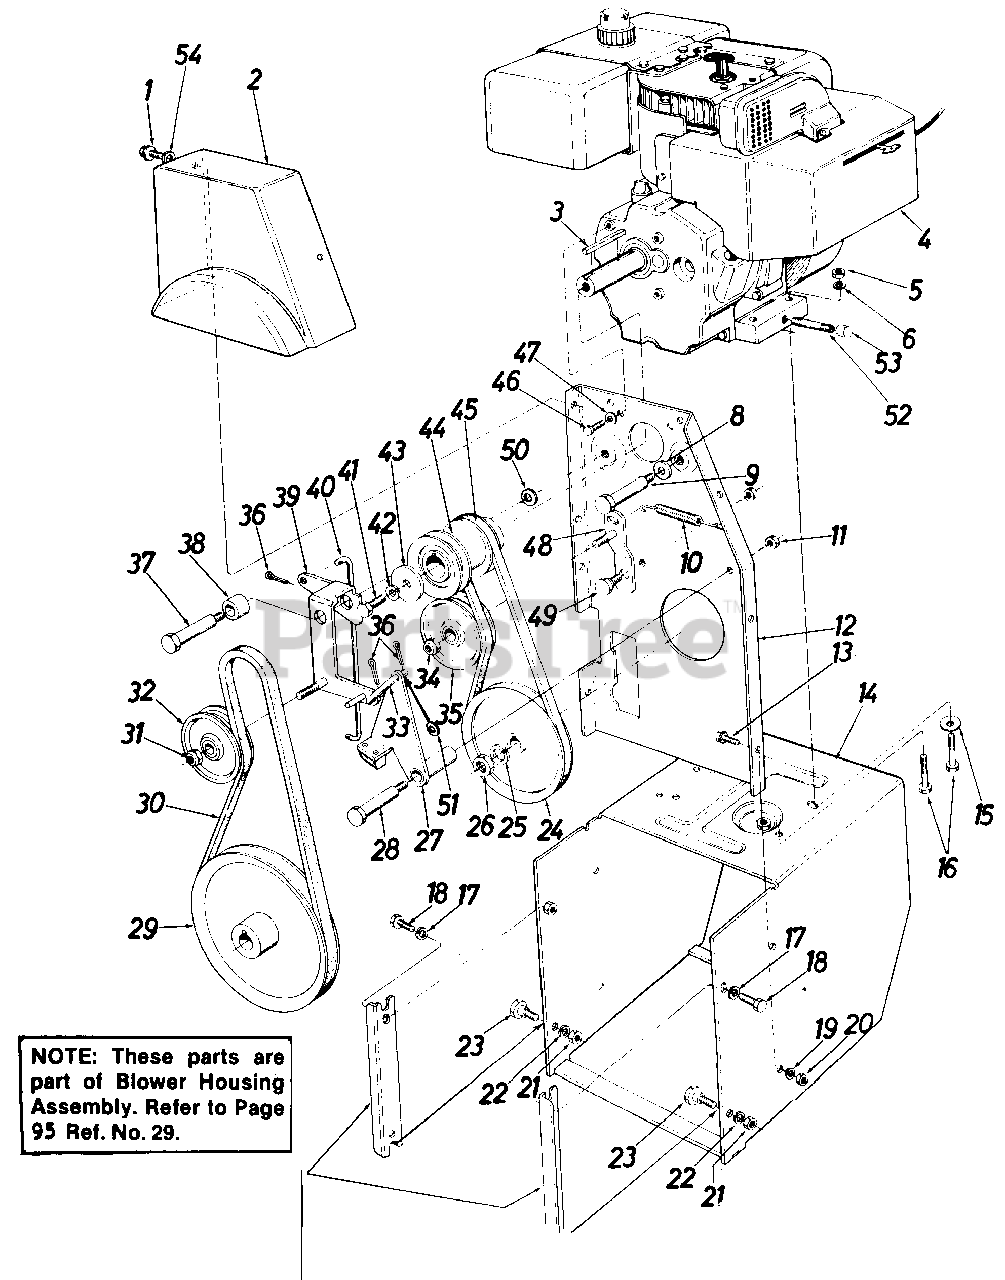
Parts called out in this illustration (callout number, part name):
1	Hex Wash. Self-Tap Scr. 5/16-24 x .50" Lg.
2	Belt Cover
3	Sq. Key 1/4" x 1.50" Lg.
4	Engine
5	Hex Nut 5/16-18 Thd.
6	L-Wash. 5/16" Scr.
8	Bell-Wash. .40 I.D. x .88 O.D.
9	Shld. Scr. .498" Dia. x 3.00" Lg.
10	Ext. Spring .38 O.D. x 3.18" Lg.
11	Hex Cent. L-Nut 3/8-16 Thd.
12	Engine Brkt. Ass'y.
13	Hex Sems Scr. 5/16-18 x .75" Lg.
14	Frame Ass'y.
15	Fl-Wash. .345 I.D. x .75 O.D. x .060
16	Hex Scr. 5/16-18 x 1.75" Lg.
17	L-Wash. 3/8" Scr. H.D.
18	Pilot Scr. 3/8-16 x,88" Lg.
19	L-Wash. 5/16" Scr.
20	Hex Nut 5/16-18 Thd.
21	Hex Nut 3/8-16 Thd.
22	L-Wash. 3/8" Scr. H.D.
23	Shld. Scr. .498" Dia. x .340" Lg.
24	V-Pulley .628 I.D. x 7.50 O.D.
25	L-Wash. for 5/8" Scr.
26	Hex Ins. Jam L-Nut 5/8-18 Thd.
27	Brake Brkt. Ass'y.
28	Shld. Scr. .498" Dia. x 2.00" Lg.
29	V-Pulley .875 I.D. x 10.12 O.D.
30	"V"-Belt 1/2" x 45.0" Lg.
31	Hex Ins. Jam Nut L-Nut 3/8-24 Thd.
32	Fl-Idler w/Flanges 3.0 O.D.
33	Brake Linkage Ass'y.
34	Hex Ins. Jam L-Nut 3/8-24 Thd.
35	3.0" O.D. Fl-Idler w/Flanges
36	Int. Cot. Pin 5/16" Dia.
37	Shld. Scr. .625 Dia. x 2.750" Lg.
38	Spacer .63 I.D. x .75 O.D. x 1.00" Lg.
41	Hex Scr. 3/8-24 x 1.25" Lg.
42	L-Wash. 3/8" Scr. H.D.
43	Fl-Wash.
44	Engine Pulley - Double Groove
45	"V"-Belt 3/8 x 35.5" Lg.
46	Hex L-Scr. 5/16-24 x .75" Lg.
47	Bell-Wash. .345 I.D. x .88 O.D. x .060
48	Drive Idler Brkt. Ass'y.
49	Shld. Scr. - .625" Dia. x .170" Lg.
50	Bell-Wash. .40 I.D. x 1.12 O.D.
51	Fl-Wash. .34 I.D. x .750 O.D. x .05
52	Pipe Nipple - 3/8" Pipe Thd. x 3.00" Lg.
53	Hex Scr. 1/4-18 Pipe Thd.
54	Fl-Wash. .340 I.D. x .88 O.D. x .62
